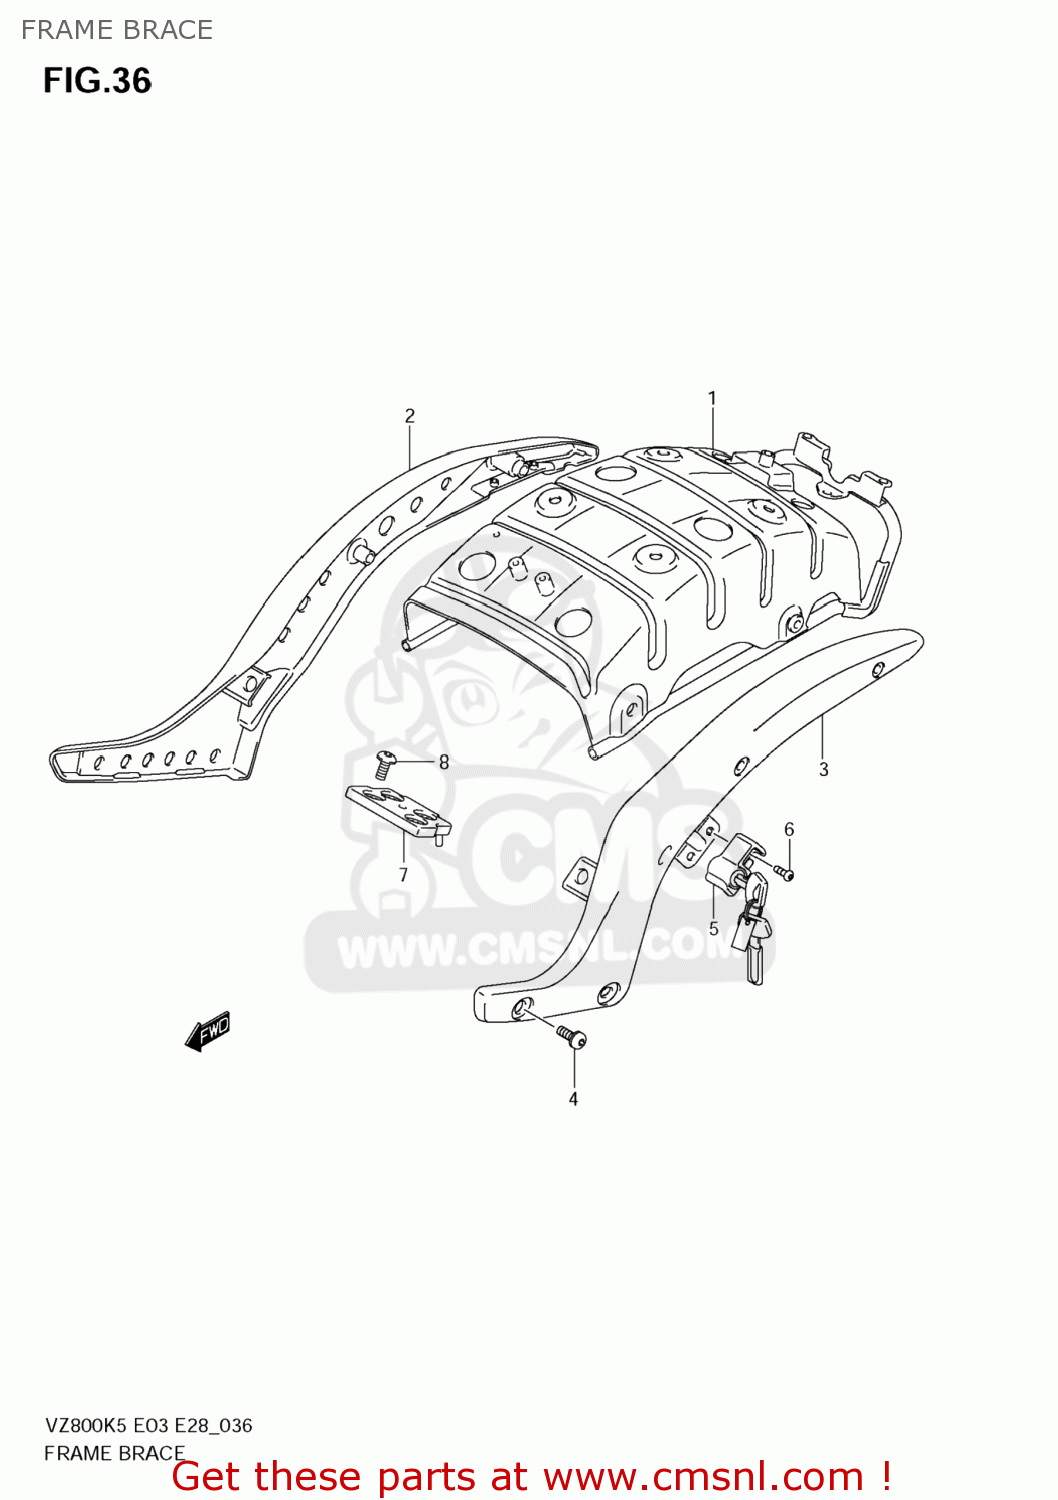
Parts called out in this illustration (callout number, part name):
1	BRACE, REAR FRAME
2	GRIP,FRAME HANDLE,R
3	GRIP,FRAME HANDLE,L
4	BOLT(10X25)
5	LOCK SET,HELMET
6	SCREW(6X14)
7	BRACKET,FUEL TANK
8	BOLT(8X16)
